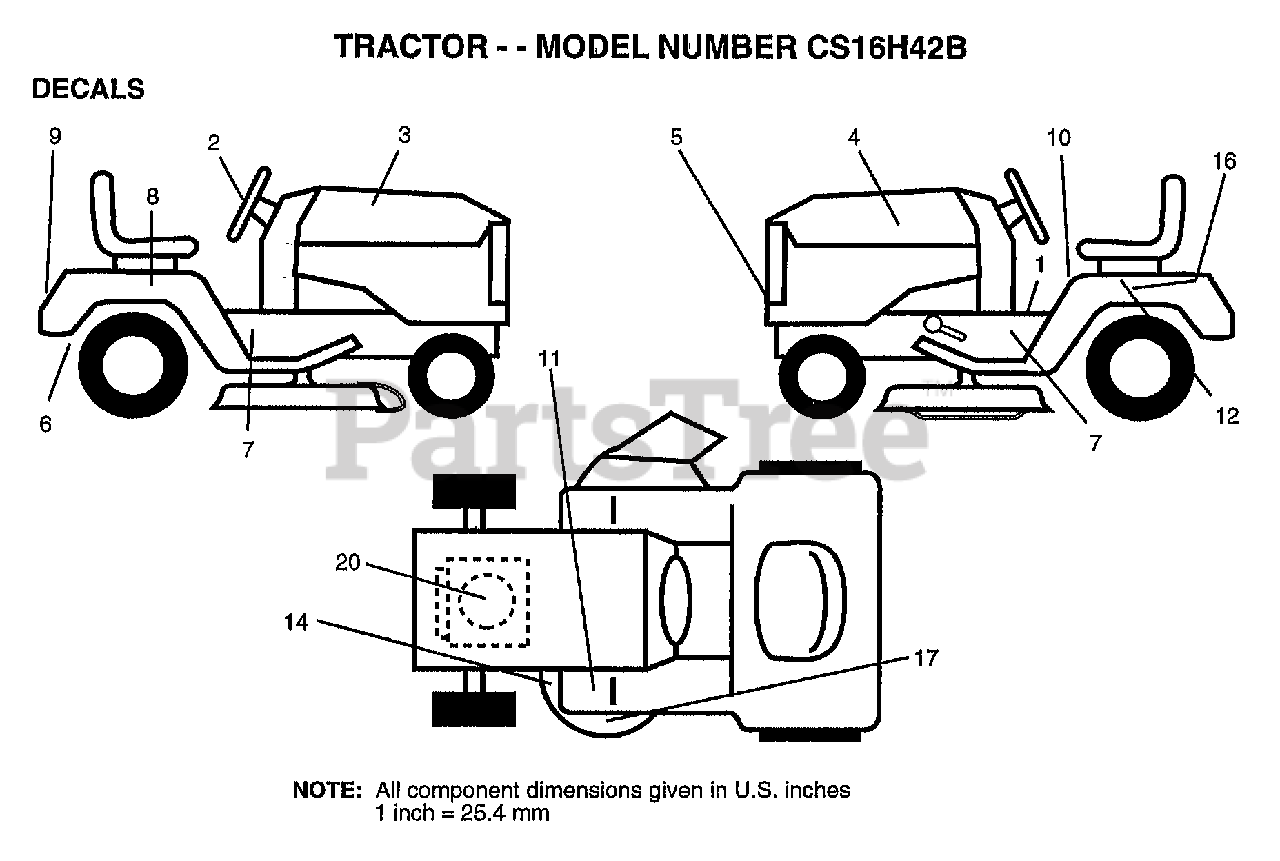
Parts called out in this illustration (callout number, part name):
1	"DECAL INST,SADDLE"
2	"DECAL INSERT,STRG"
3	"DECAL.HOOD,RH"
4	"DECAL.HOOD,LH"
5	DECAL.LENS.YP.EUR
6	DECAL DRAWBAR LH
7	DECAL CHASSIS
8	DECAL FENDER RH
9	DECAL FENDER
10	"DECAL DANGER,FEND"
12	DECAL FENDER LH
14	"DECAL-SCHEM,BELT"
16	DECAL.BATRY.3-3908
17	"DECAL,ENVIRO DECK"
20	DECAL, HP ENGINE
